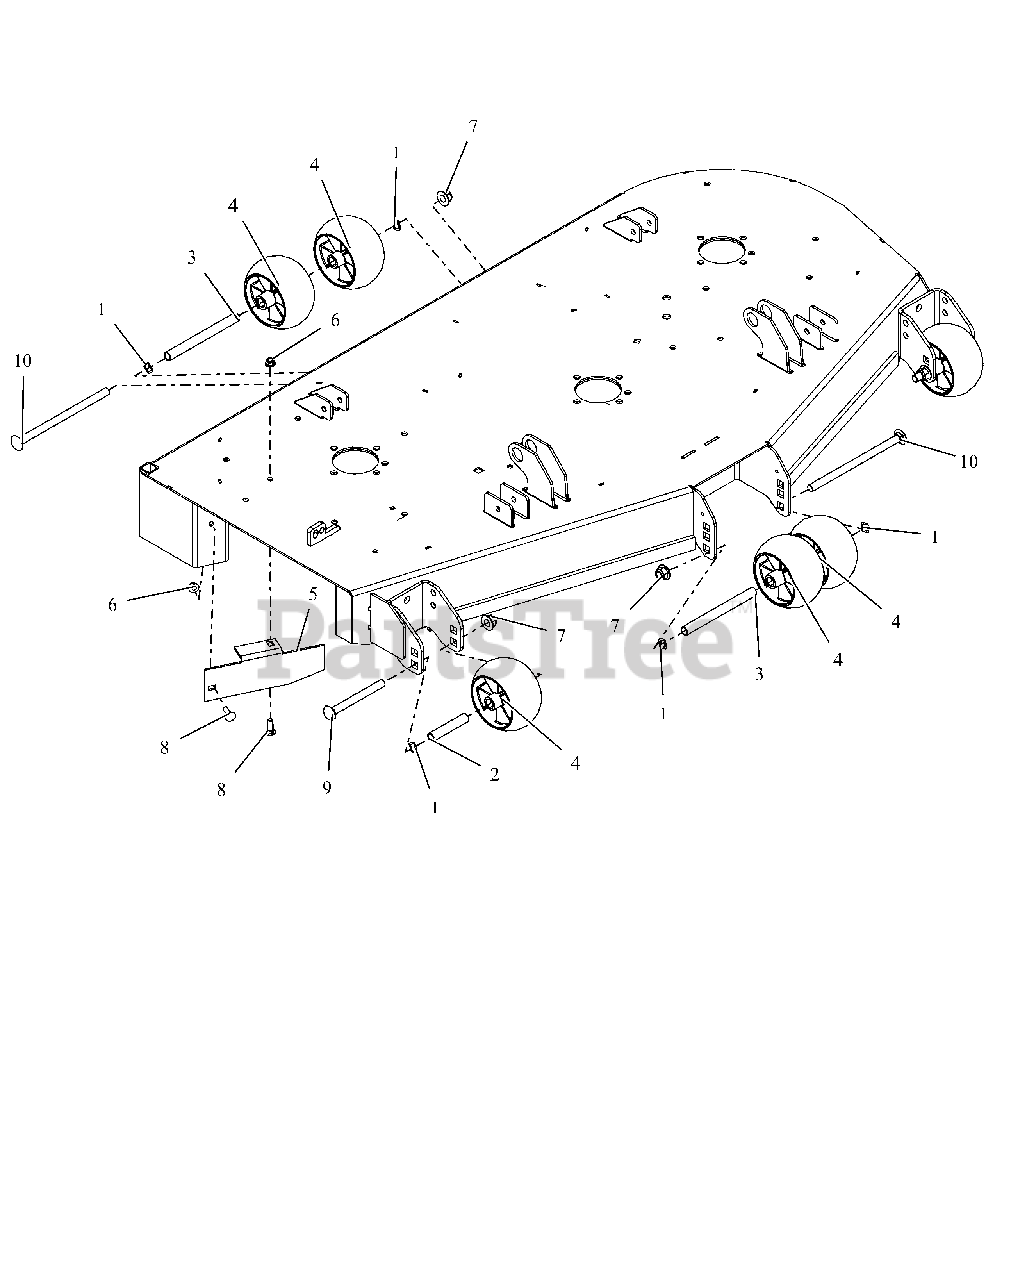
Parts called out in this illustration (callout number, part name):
1	WAVE WASHER .531X.781X.125FH
2	SPACER, .510X.625X3.35
3	SPACER, .510X.625X6.50
4	ANTI-SCALP WHEEL - 5X3 CTR
5	BAFFLE, DISCHARGE, 52"
6	NUT,NYL-FLG .31-18 GF ZCC
7	NUT,NYL-FLG .50-13 GF ZCC
8	BLT,RHSN .31-18X1.00 G5 ZCC
9	BLT, RHSN .50-13X5.00 G5 ZCC
10	BLT, RHSN .50-13X8.50 G5 ZCC
